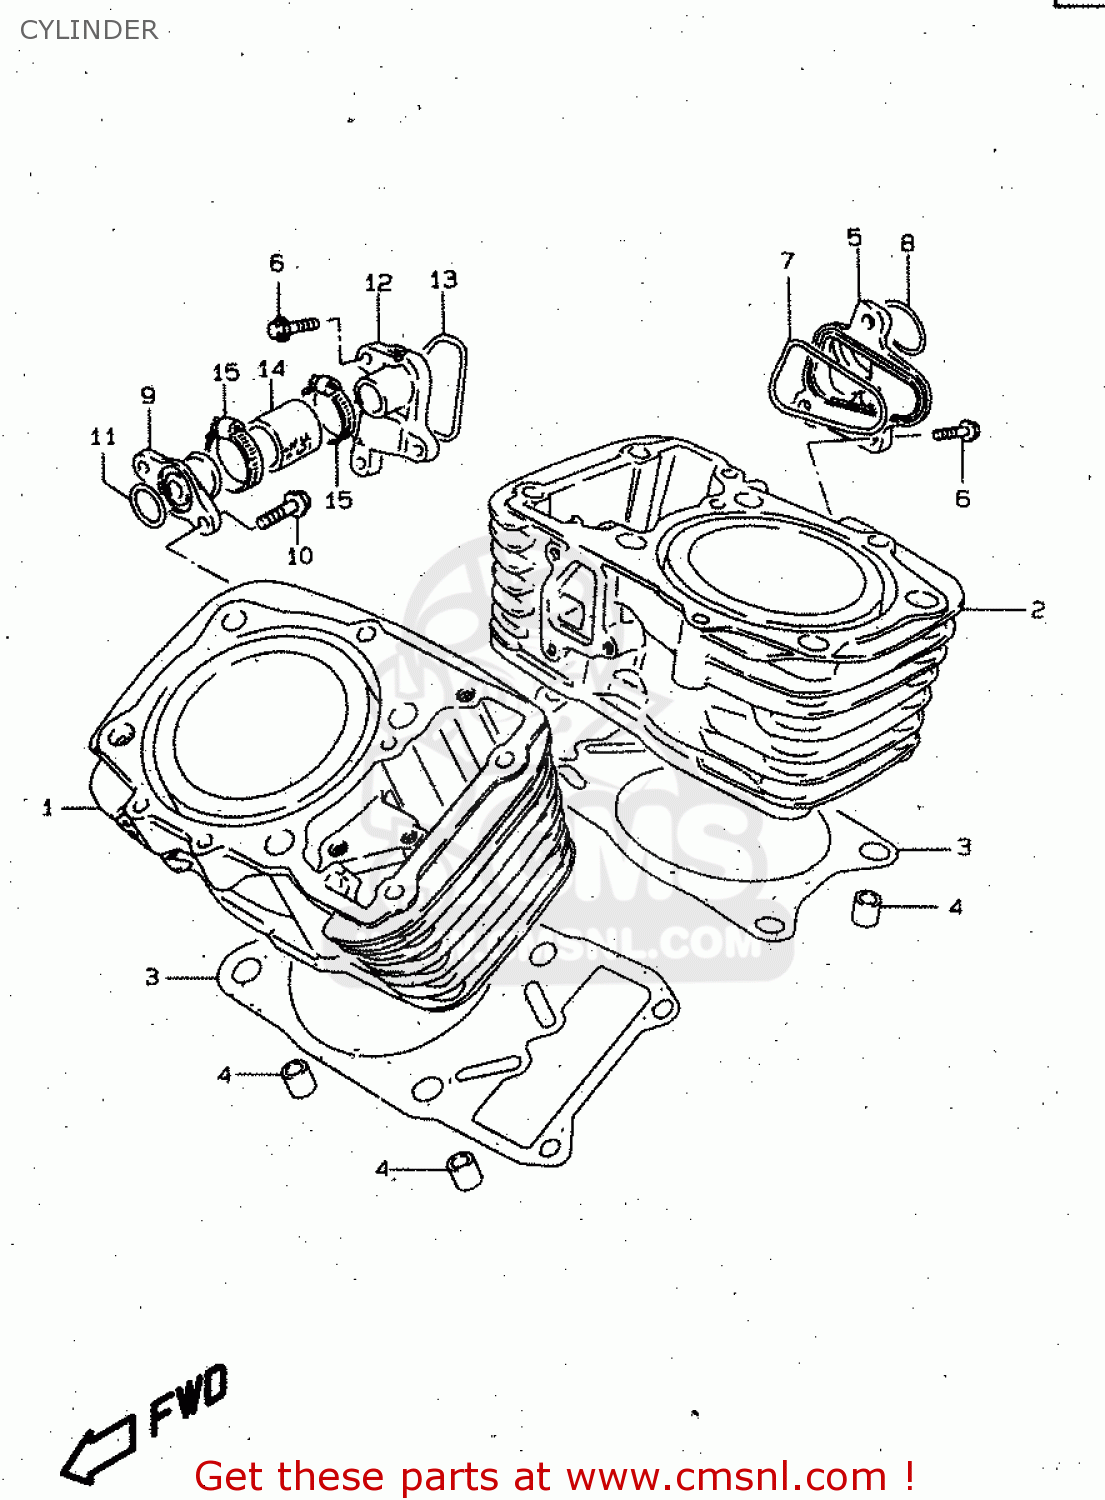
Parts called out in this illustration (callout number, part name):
1	CYLINDER,FR
2	CYLINDER
3	GASKET,CYLINDER
4	PIN
5	CHAMBER,WATER,INLET
6	BOLT
7	O RING,INLET WATER CHAMBER
8	O RING(D:2.3,ID:24.4)
9	UNION,WATER INLET
10	BOLT
11	O RING(D:2.4,ID:15.8)
12	CHAMBER,WATER OUTLET
13	O RING,OUTLET WATER CHAMBER
14	HOSE,RADIATOR INLET
15	CLAMP
